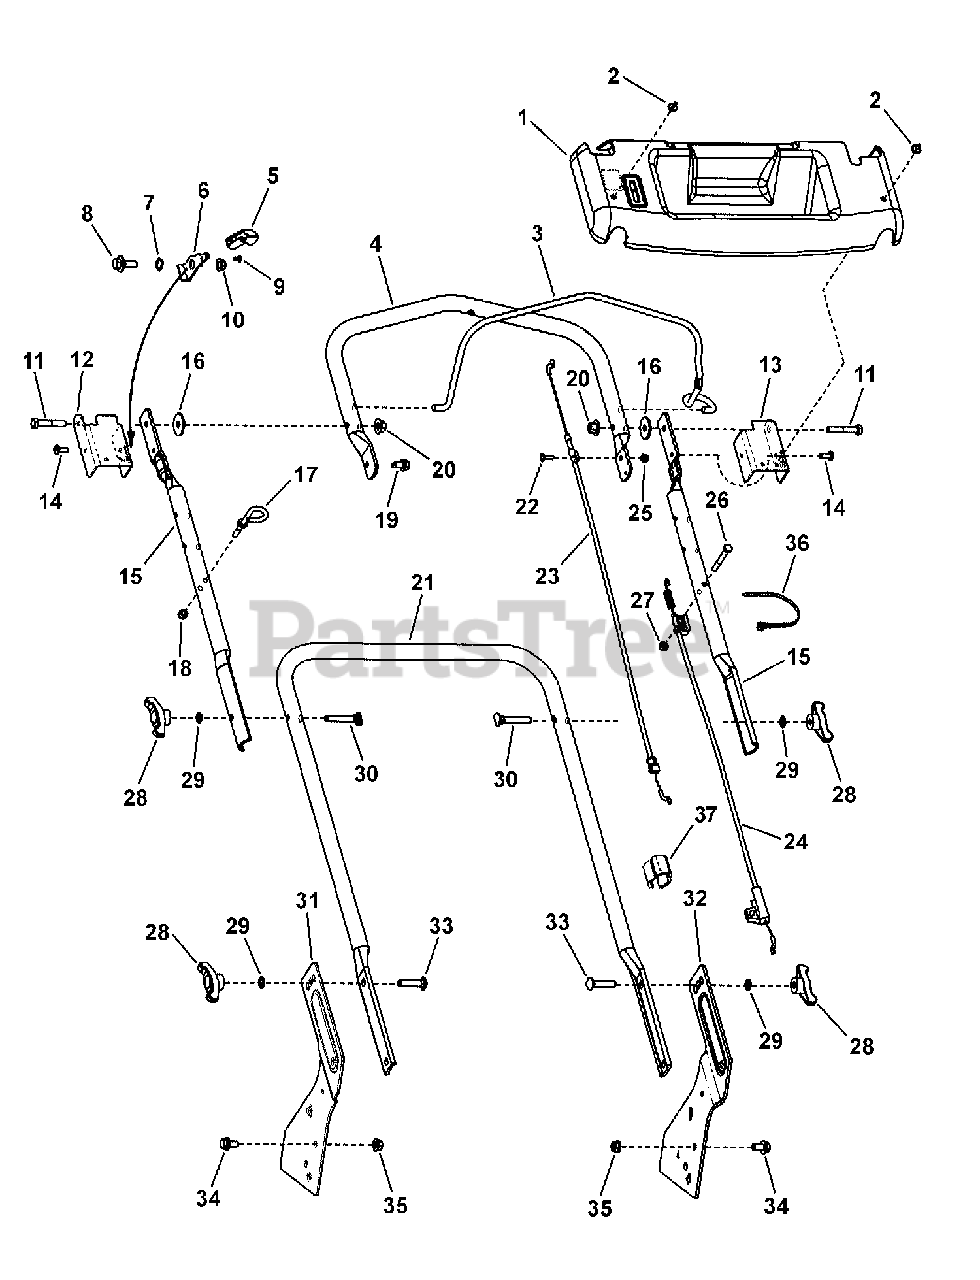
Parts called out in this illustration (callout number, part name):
1	PANEL, Upper Handle, Snapper 21 WBM
2	RIVET, Pop .250 Dia.
3	BAIL, Pivot Handle
4	HANDLE, Pivot
5	LEVER, Lock Handle
6	HANDLE, Lock
7	WASHER, .531 x .781 Wave
8	BOLT, 5/16-18 Shoulder
9	RIVET, Plastic Snap
10	NUT, 5/16-18 Flange Lock, YZ
11	SCREW, 5/16-18 x 1-3/4" Hex Head Cap, GR 5
12	BRACKET, Rotation Limit, RH
13	BRACKET, Rotation Limit, LH
14	SCREW, 1/4-20 x .55 Torx Self-Tap
15	HANDLE, Upper, Straight, 22"
16	WASHER, 5/16 Nylon
17	ROPE GUIDE, (1/4-20 thread)
18	NUT, 1/4-20 Hex Nyloc
19	SCREW, 5/16-18 x 5/8" Hex Washer Self-Tap
20	NUT, 5/16-18 Large Head Center Lock, Black
21	HANDLE, Lower
22	BOLT, #10-24 x 1/2" Flat Head Square Neck
23	CABLE, OPC, 22", Pivot Handle
24	CABLE, Drive, 22", Pivot Handle
25	NUT, #10-24 Hex Nyloc
26	SCREW, 1/4-20 x 2", Hex Head Cap, GR 5
27	NUT, 1/4-20 Hex Center Lock
28	KNOB, 5/16-18 Wing (Black)
29	WASHER, 5/16" Internal Tooth Lock
30	BOLT, 5/16-18 x 2" Curved Head Square Neck, GR 2
31	BRACKET, Lower Handle RH 22" WBM
32	BRACKET, Lower Handle, LH 22" WBM
33	BOLT, 5/16-18 x 1-1/2" Round Head Square Neck
34	BOLT, 5/16-18 x 5/8" Hex Flange Lock, YZ
35	NUT, 5/16-18 Flange Lock, YZ
36	WIRE TIE, 11 Inch Standard Black Nylon
37	CLIP, Cable, Double
